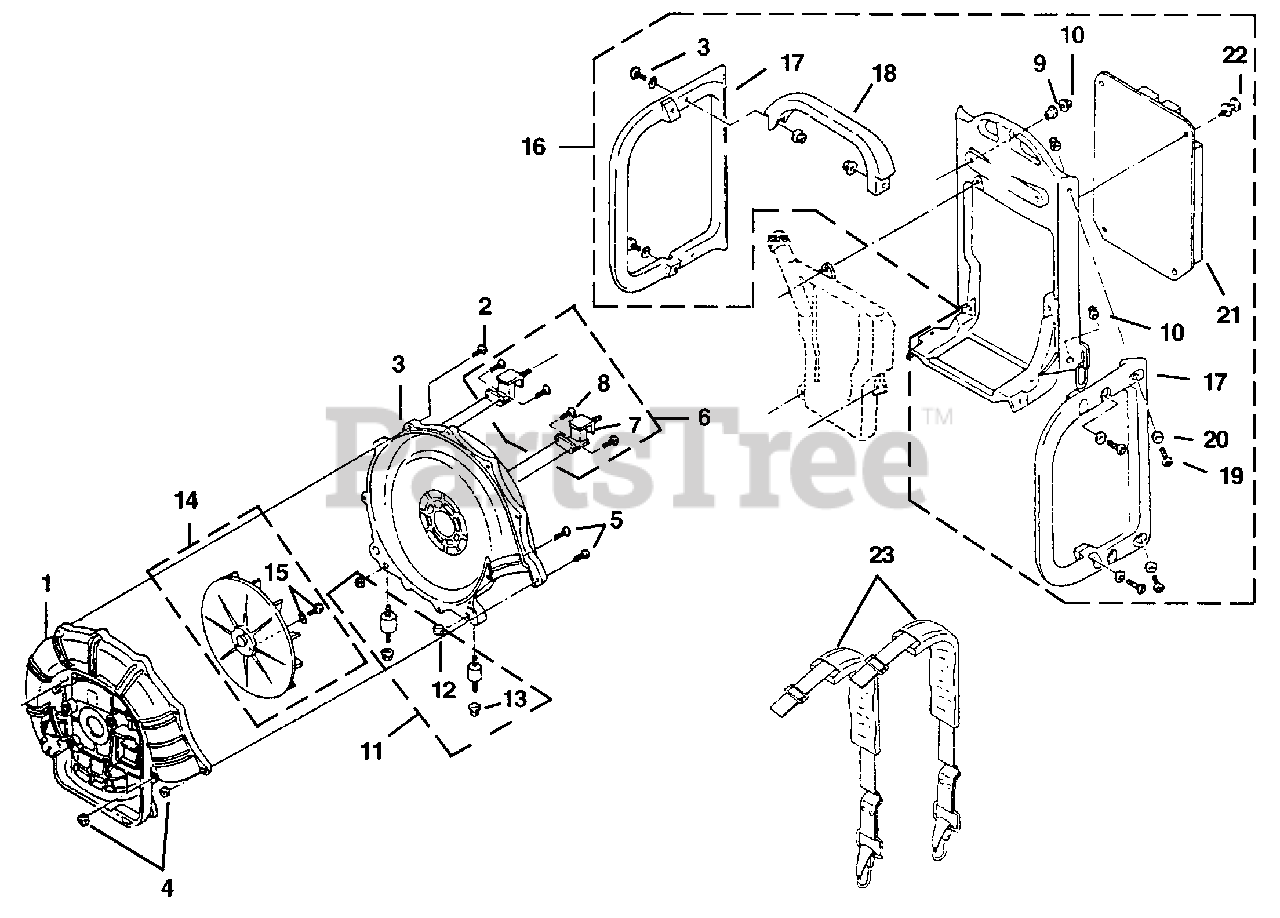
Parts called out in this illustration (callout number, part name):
1	VOLUTE-Outer
2	SCREW-Tapping (M5 x 25)
3	VOLUTE-Inner
3	SCREW ASSEMBLY (M5 x 25 W SW)
4	NUT (M5)
5	SCREW ASSEMBLY (M5 x 25 W SW)
6	ISOLATORS-Upper
7	BRACKET-Isolator
8	SCREW-Self Tapping (M5 x 10)
10	NUT-Flange
10	NUT-Flange (M5)
11	ISOLATORS-Lower
12	NUT (M6 x 5)
13	NUT-Flange
14	FAN ASSEMBLY
15	BOLT ASSEMBLY
16	FRAME COMPLETE
17	FRAME-Side
19	SCREW-Pan Hd (M5 x 20)
20	WASHER(M5)
22	RIVET-Lock
23	SHOULDER HARNESS
